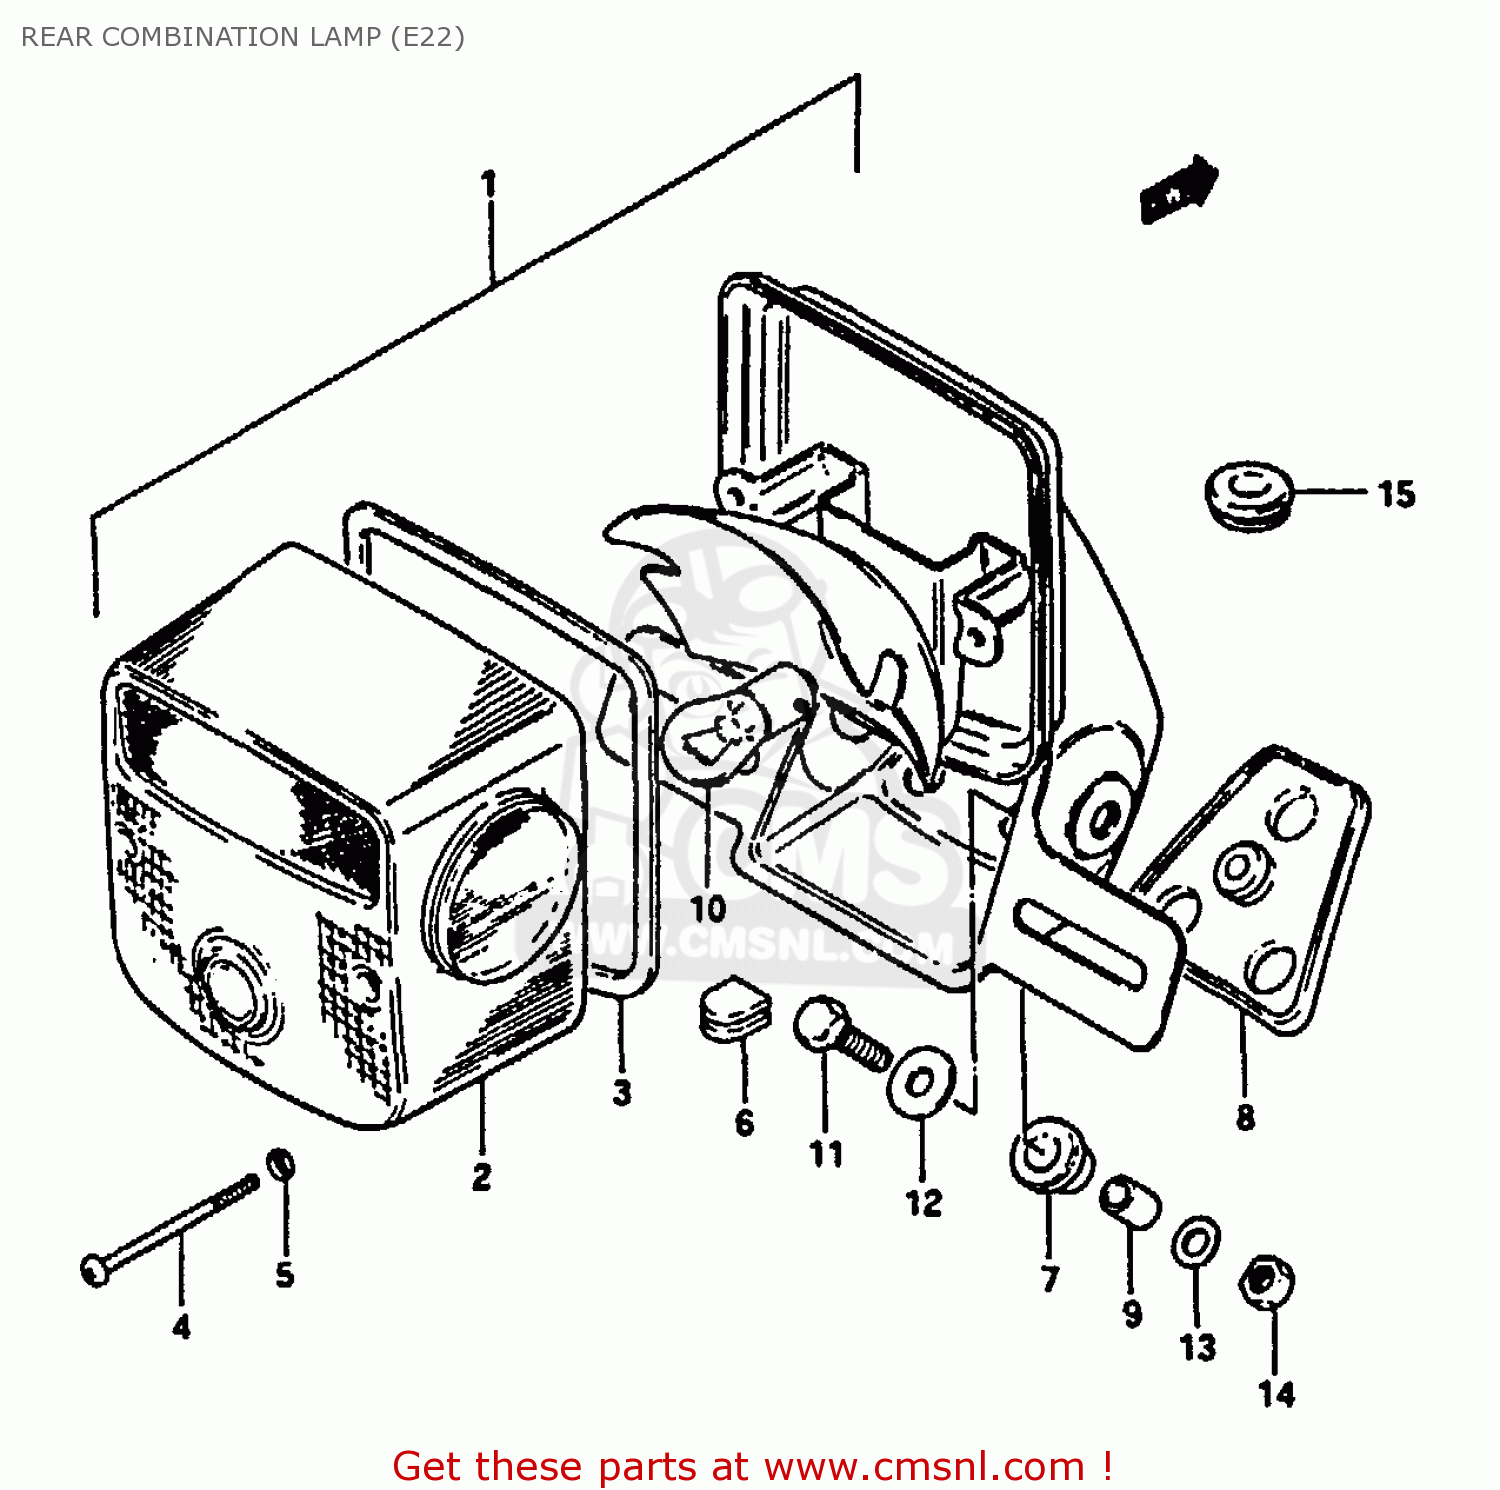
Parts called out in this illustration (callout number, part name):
1	LAMP ASSY,TAIL
2	LENS
3	GASKET (NAS)
4	SCREW (4X55)
5	GASKET (NAS)
6	GROMMET,REAR COMBINATION LAMP
7	CUSHION
8	CUSHION
9	SPACER
10	BULB(12V21/5W)
11	BOLT
12	WASHER (6.5X20X1.2)
13	WASHER
14	NUT
15	GROMMET
